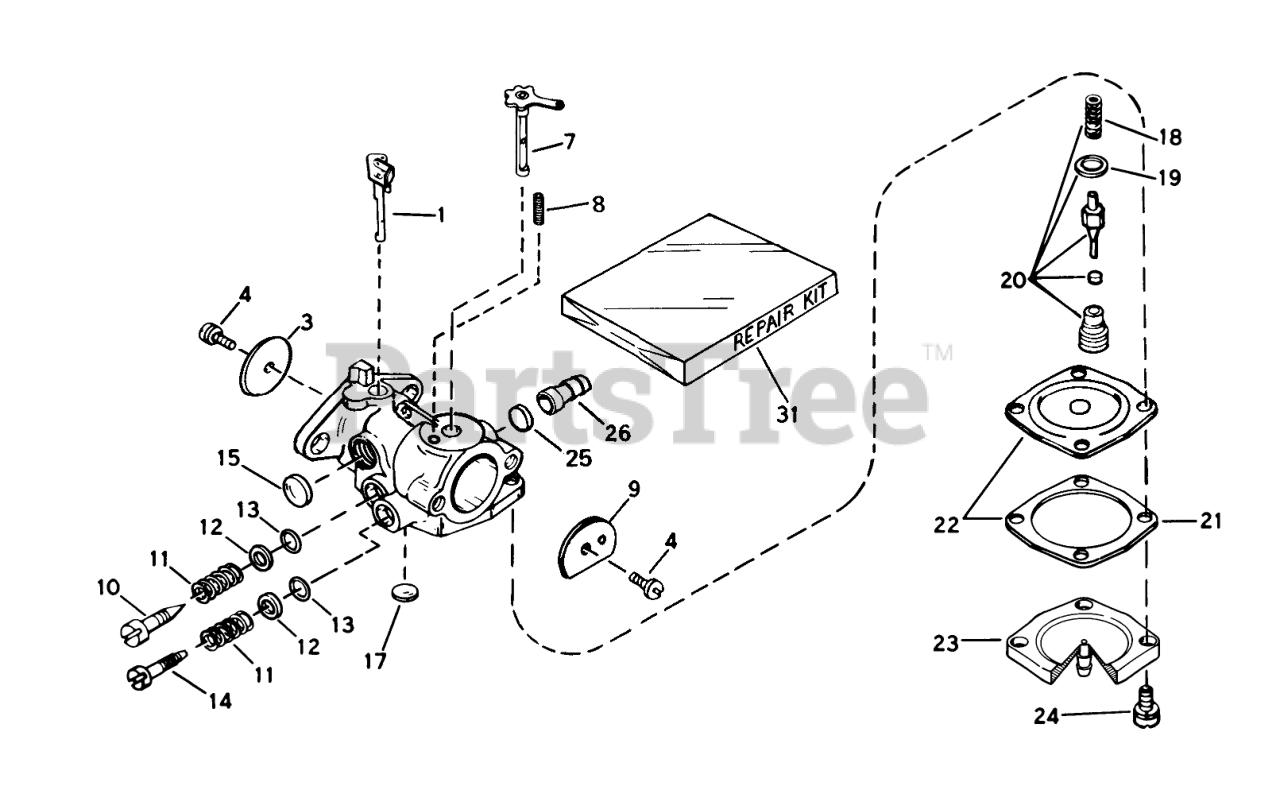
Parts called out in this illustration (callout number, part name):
1	Shaft/Lever-Throttle
3	Shutter-Throttle
4	Screw-Shutter
7	Shaft & Lever Assembly
8	Spring-Positioning, Choke
9	Shutter-Choke
10	Screw-Idle Adjustment
13	"O"Ring
14	Screw Main Adjustment
15	Plug-Welch, Idle Mixture Well
17	Plug Welch
18	Spring-Valve
19	Gasket-Valve Seat
20	Inlet Needle, Seat, Spring & Gasket Assembly (Incl. Ref. #18 & 19)
21	Gasket-Diaphragm
22	Diaphragm Assy. (Incl. Ref. #21)
23	Cover-Diaphragm
26	Fitting-Fuel
31	Kit-Repair
